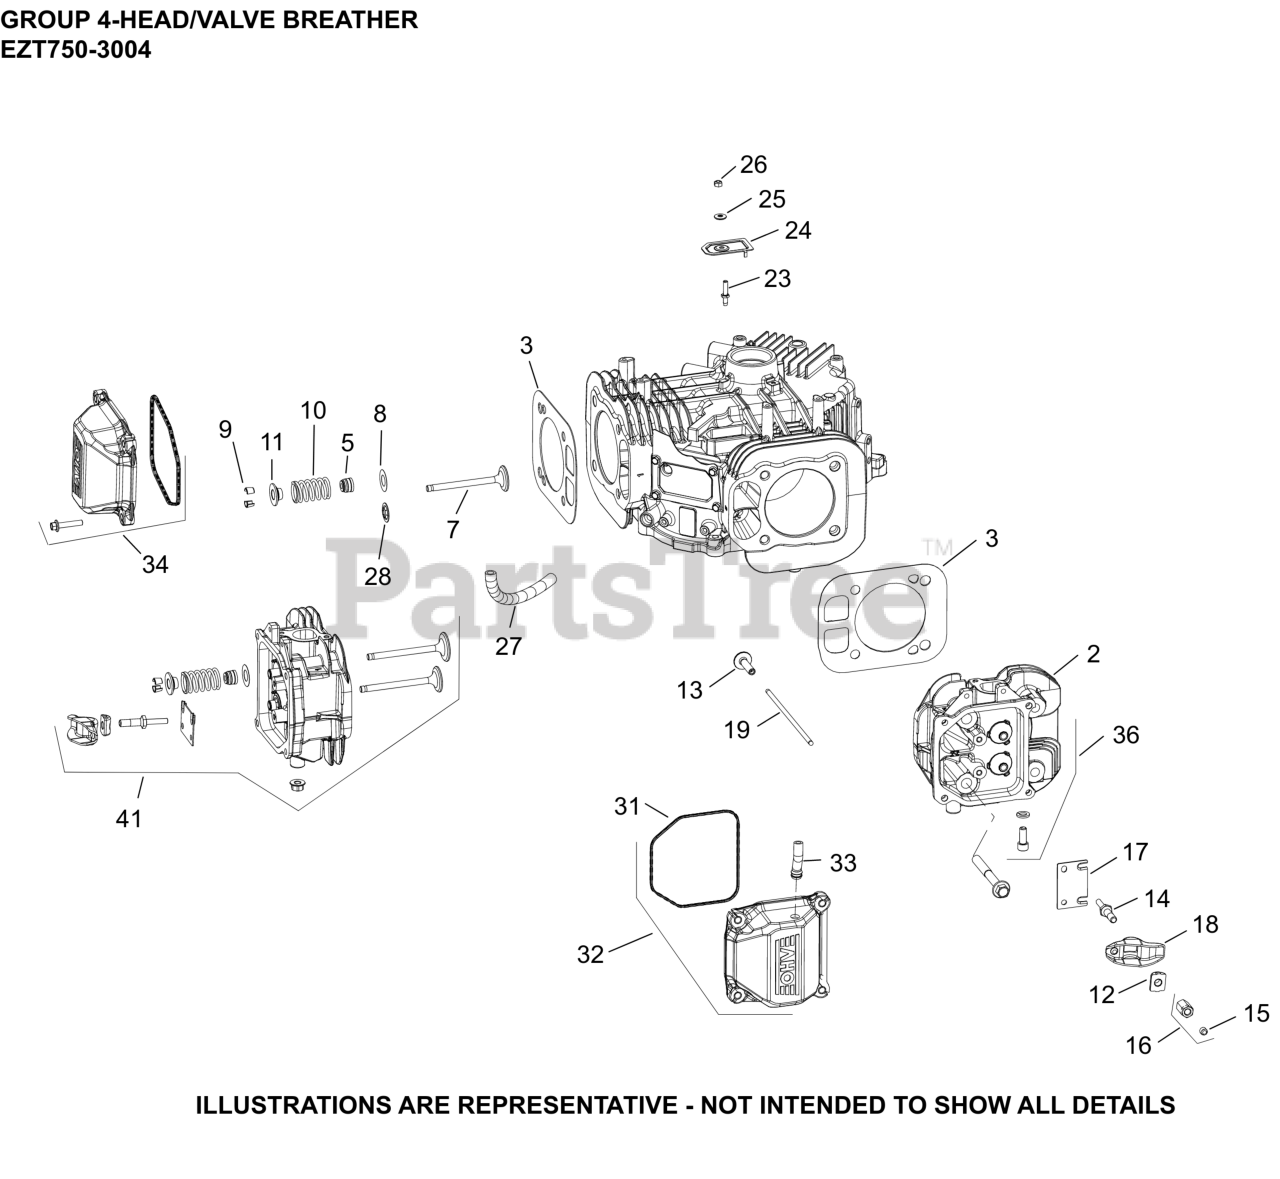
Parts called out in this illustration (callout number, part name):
3	KIT, GASKET CYLINDER HEAD
5	SEAL, VALVE BAND
7	VALVE, EXHAUST
7	VALVE, EXHAUST (.25)
8	SPACER (.010")
9	KIT, RETAINER
10	SPRING VALVE
11	CAP, VALVE SPRING
12	PIVOT, ROCKER ARM
14	STUD, ROCKER
15	SCREW, SET
16	HEX NUT ASSEMBLY
17	PLATE, GUIDE
18	ARM, ROCKER
19	ROD, PUSH
24	COVER, BREATHER REED
25	WASHER, SEALING
26	NUT, LOCK M5X.8
27	HOSE, BREATHER
28	RETAINER, VALVE GUIDE (KM)
31	O-RING (YELLOW), VALVE CO
32	KIT,BREATHER VALVE COVER (PLASTIC)
33	HOSE, FP-USE 32 326 07-S(PLASTIC COVERS)
34	KIT, VALVE COVER-PLAIN (PLASTIC)
36	KIT, HEAD #2 AND HARDWARE-(#1675521S)
41	KIT, CYLINDER HEAD #1
NI	VALVE, INTAKE (STD)
NI	VALVE, INTAKE (.25)-(#DSC)
NI	SCREW, HEX FLANGE M10 X 1.5-6g X 90mm
NI	SCREW, HEX FLANGE (M6 X 31.625 DOG PT)
